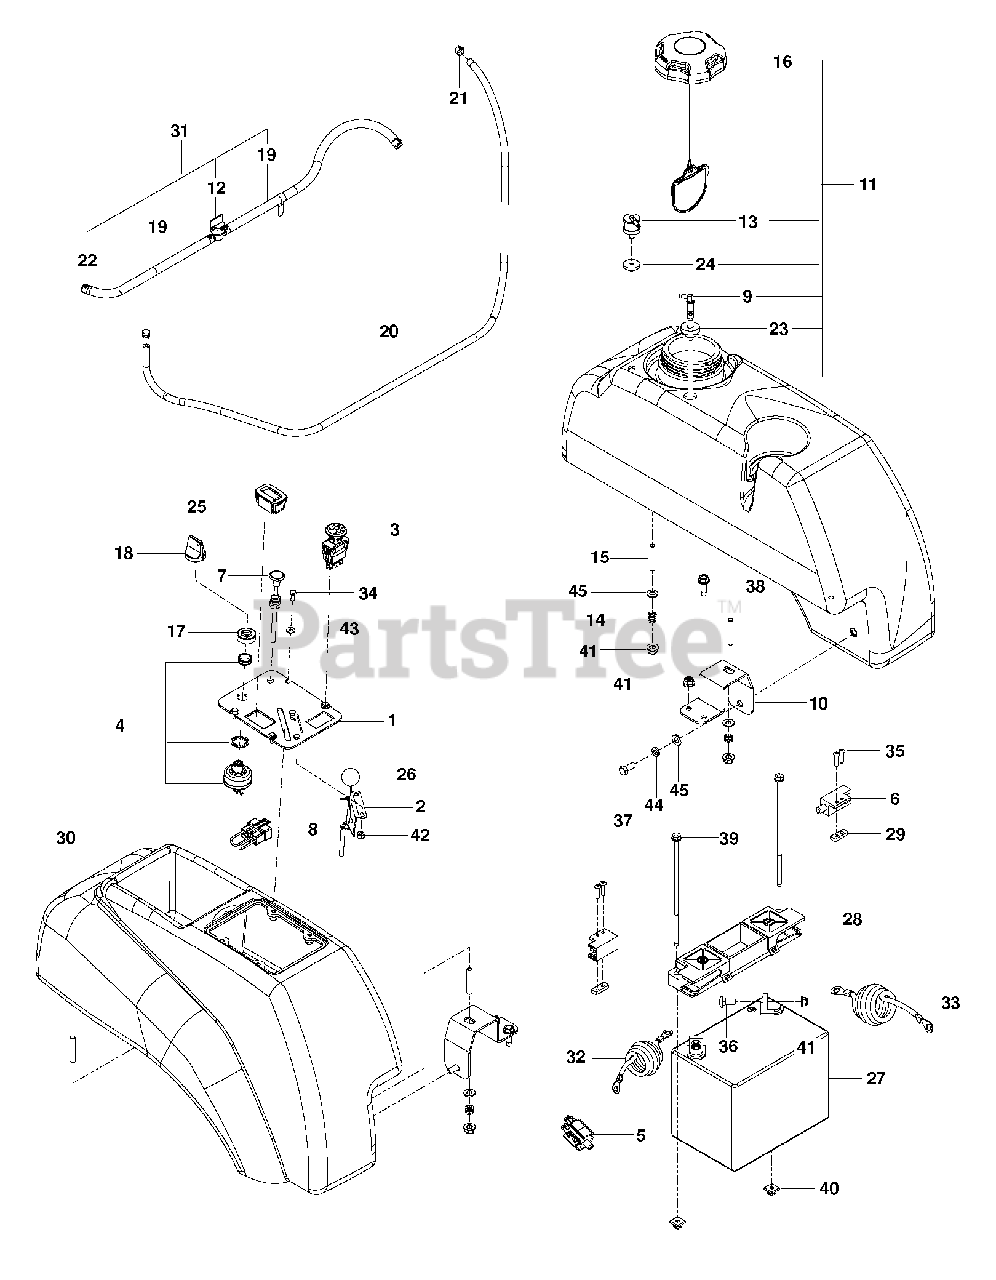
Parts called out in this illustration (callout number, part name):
1	PLATE.CONSOLE.BLACK
2	THROTTLE CABLE
3	SWITCH, PTO 10 AMP
4	SWITCH, IGNITION, INDAK
5	SWITCH, BRAKE 3P
6	SWITCH INTERLOCKT
7	CHOKE CABLE
8	PLUG, TIMER
9	FITTING, FUEL
10	SUPPORT, TANK, BLK
11	FUEL.TANK.ASSY.LH.MZ.GRY
12	FUEL VALVE
13	VALVE.FUEL.CHECK
15	STUD, 5/16C
16	CAP, FUEL
17	CAP IGNITION NUT
18	KEY, IGNITION
19	GAS LINE 10"
20	HOSE.3/16"VAPOR.27"
21	CLAMP, HOSE
22	HOSE CLAMP
23	RUBBER GROMMET
24	GROMMET, CHECK VALVE
25	RP GUAGE.SRVCMNDR.HRMTR.
26	KNOB.ROUND.BALL.BLACK
27	BATTERY, 12 V 330 AMP
28	BATTERY HOLD DOWN
29	TAPPED PLATE
30	FENDER CONSOLE
31	FUEL LINE ASM
32	POST.CABLE LONG
33	NEG. CABLE, 28"
34	HCS #10-24 X 1/2
35	SCR #10-24 X .75 SKT HD BLK
36	BOLT 5/16C X 3/4" CARRIAGE
37	HCS 5/16C X 3/4
38	RP BLT 5/16-18 X 1 THRD FORM D
39	Bolt, 1/4-20 X 7.5
40	PUSH NUT-NYLON
41	5/16-18 NYLOC FLANGE NUT
42	NUT 10-24 NYLOC
43	WASHER #10
44	WASHER 5/16 LOCK
45	FLAT WASHER 5/16 SAE
